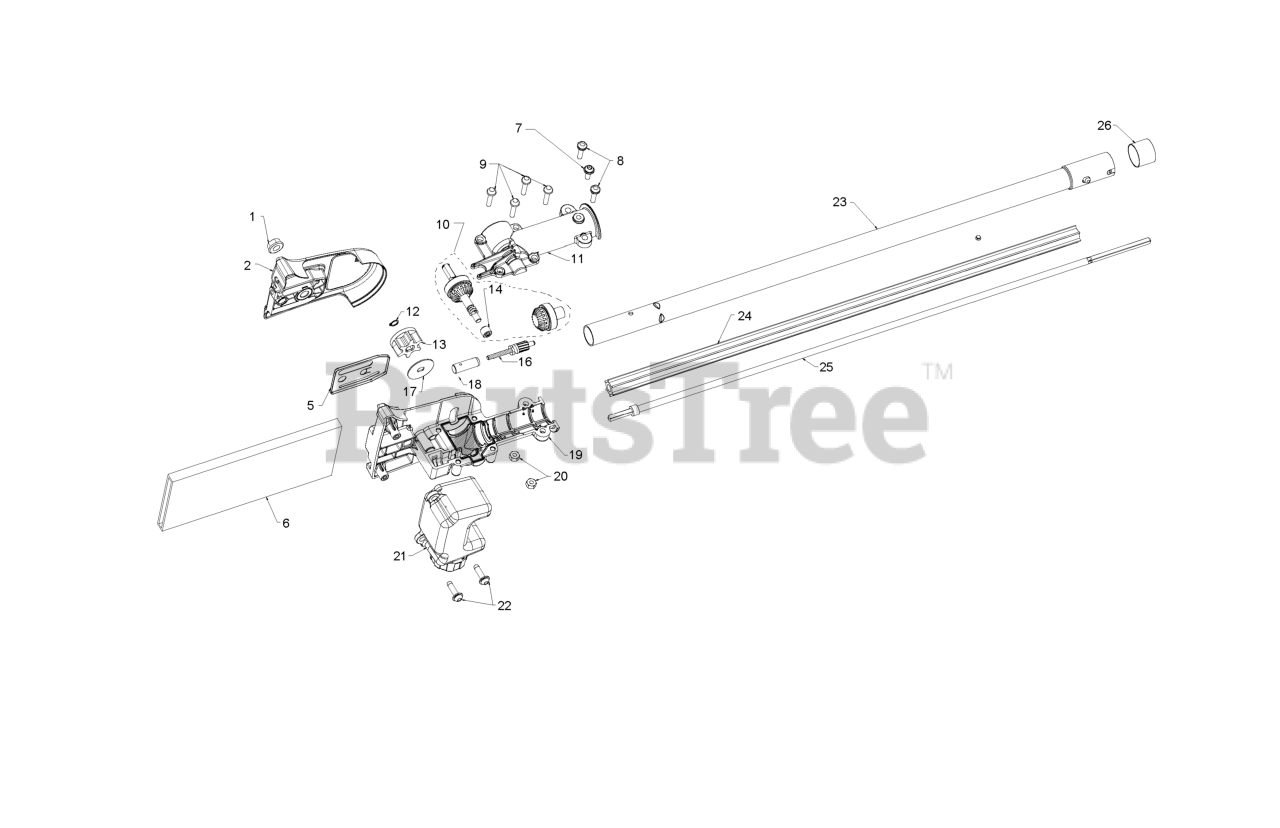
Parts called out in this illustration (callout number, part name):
2	CLAMP ASSY
5	PAD BAR PLATE
7	SCREW-10-14 X 1/2 PLASTITE
8	SCR 10-24 MS LDK PAN PH
9	SCREW-10-14 X 13/16 (PL
10	KIT GEAR ASSY
11	COVER GEAR HOUSING
12	RING SPROCKET RETAINER
16	ASSY GEAR PLUNGER
18	OIL BLOCK ASSY
19	HOUSING POLE SAW GEAR
20	LOCKNUT-HEX 10-24
21	ASSY OIL TANK
25	FLEX-LOWER
